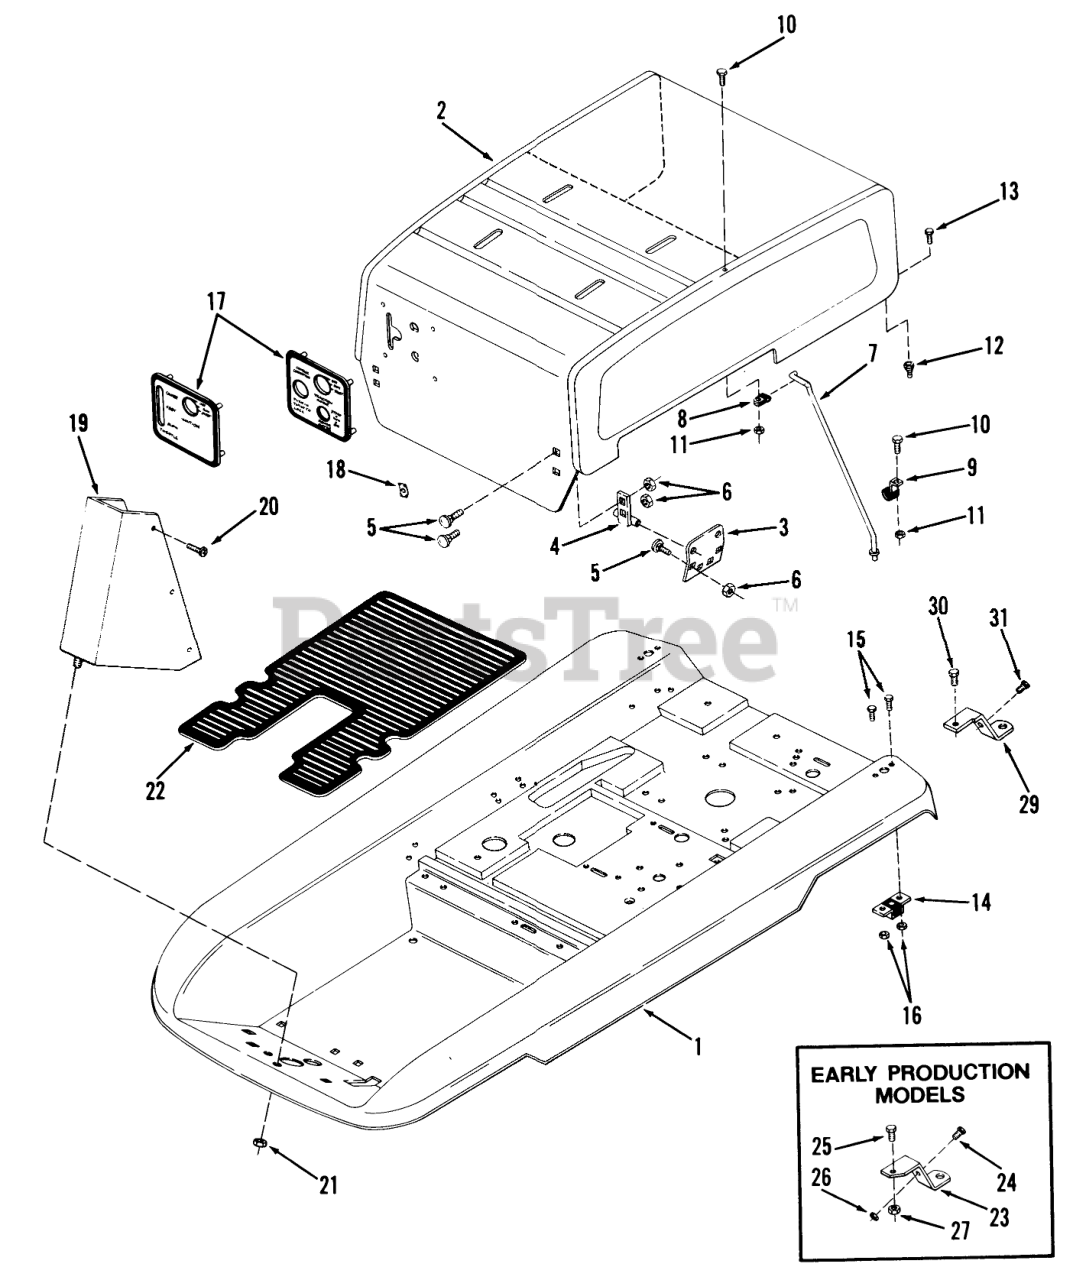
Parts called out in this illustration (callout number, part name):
3	BRACKET R
4	Seat Pivot
5	Bolt
6	Nut
7	ROD-HOOD SUPPORT
9	Clip-Hood Support Rod Rear
10	H H C S
11	Nut
12	Ball Stud
14	Stud Latch
15	Bolt
16	Nut
17	Control Panel
17	PANEL-GAS CONTROL
18	SPEED NUT
19	Shroud
20	Screw 1/4-20 X 3/8-Early Production Models Only
20	Screw-Hex HD Slotted
21	Nut
22	Floor Mat
23	Hitch Bar
24	Bolt
25	Bolt
26	Nut
27	Nut
28	WASHER 5/16 SAE
29	Drawbar Hitch
30	H H C S
31	Bolt, 3/8-16 x 1/2
